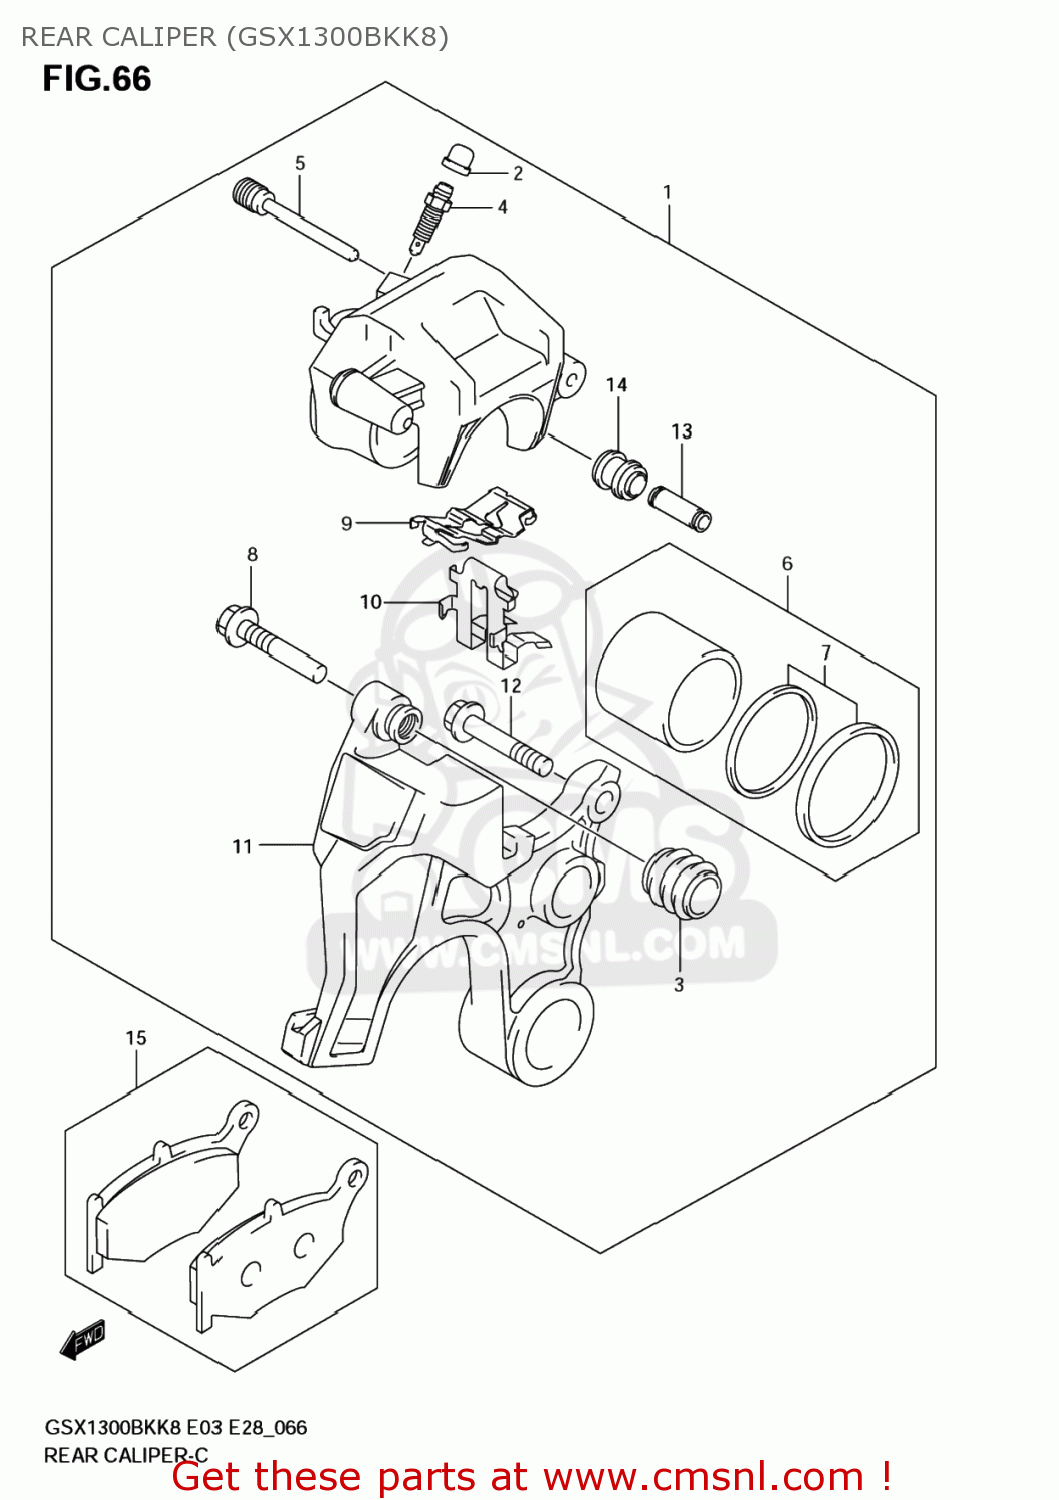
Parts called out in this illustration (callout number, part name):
1	CALIPER ASSY,RR
2	CAP,BLEEDER PLUG
3	BOOT,AXLE
4	BLEEDER
5	PIN,PAD
6	PISTON SET
7	SEAL SET,PISTON
8	PIN,BOLT
9	SPRING,PAD
10	RETAINER
11	BRACKET
12	BOLT
13	SLEEVE
14	BOOT,SLEEVE
15	PAD SET (NAS)
